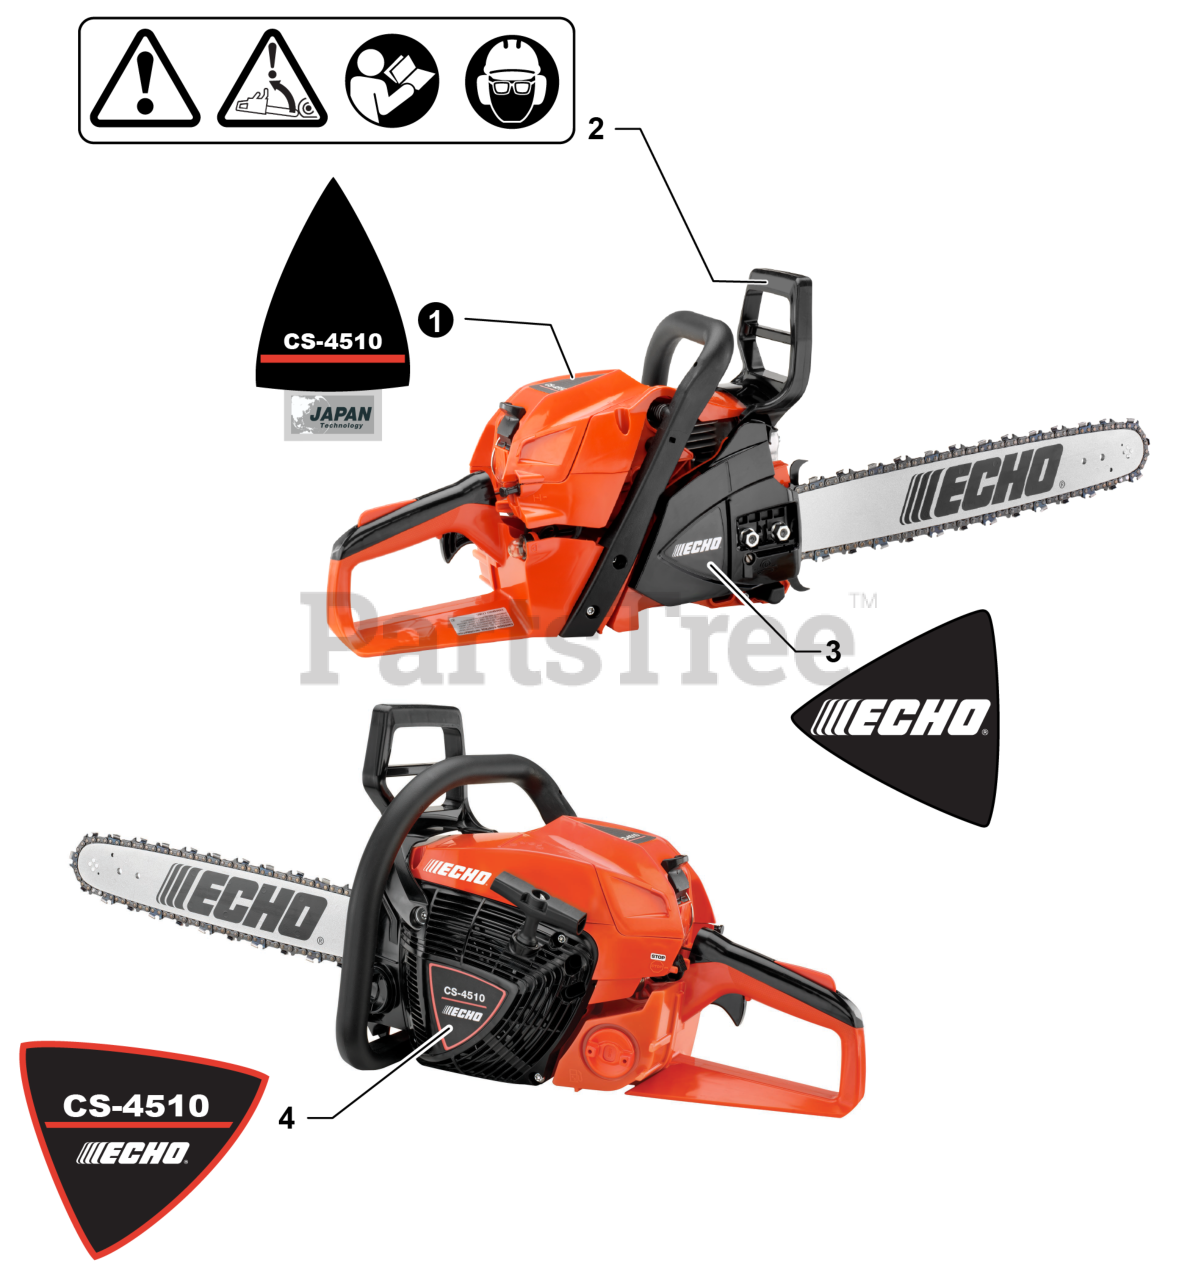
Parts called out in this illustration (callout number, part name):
1	LABEL - MODEL CS-4510
2	LABEL - CAUTION
3	LABEL - ECHO
4	LABEL - MODEL CS-4510
